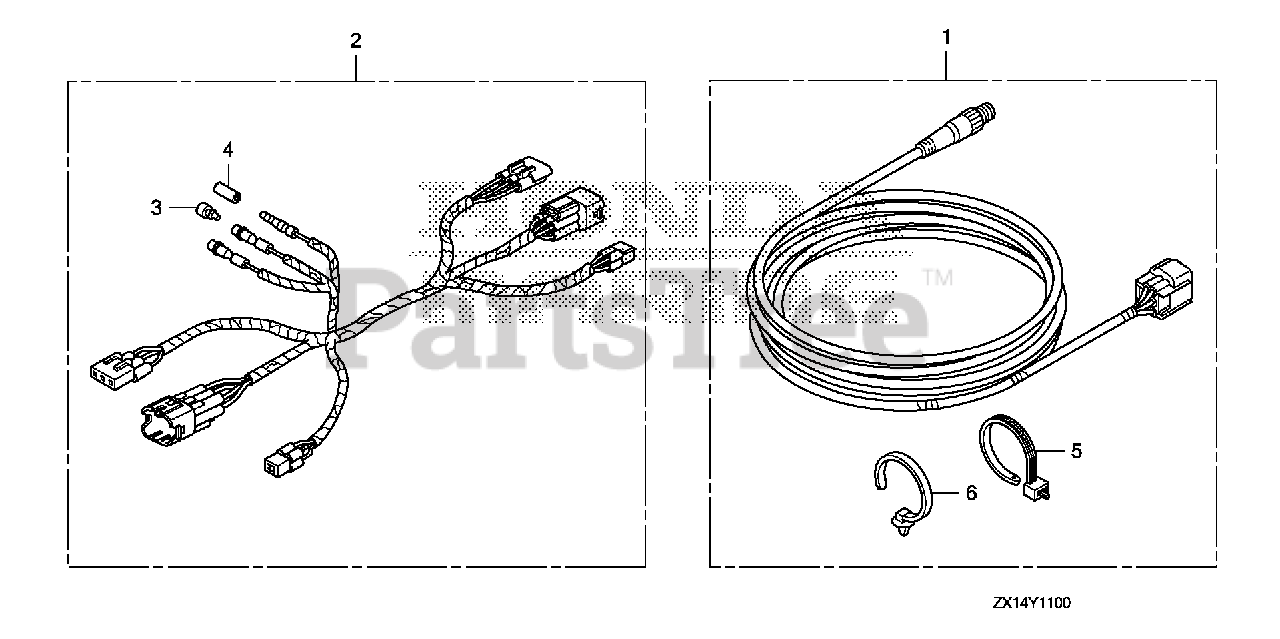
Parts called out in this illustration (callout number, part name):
1	KIT, CABLE (6FT) (NMEA)
2	HARNESS ASSY., REMOTE CONTROL SUB
3	PLUG, CONNECTOR (INNER)
4	PLUG, CONNECTOR (OUTER)
5	TIE, CABLE
6	CLIP, HARNESS BAND (155.3MM) (BLACK)
